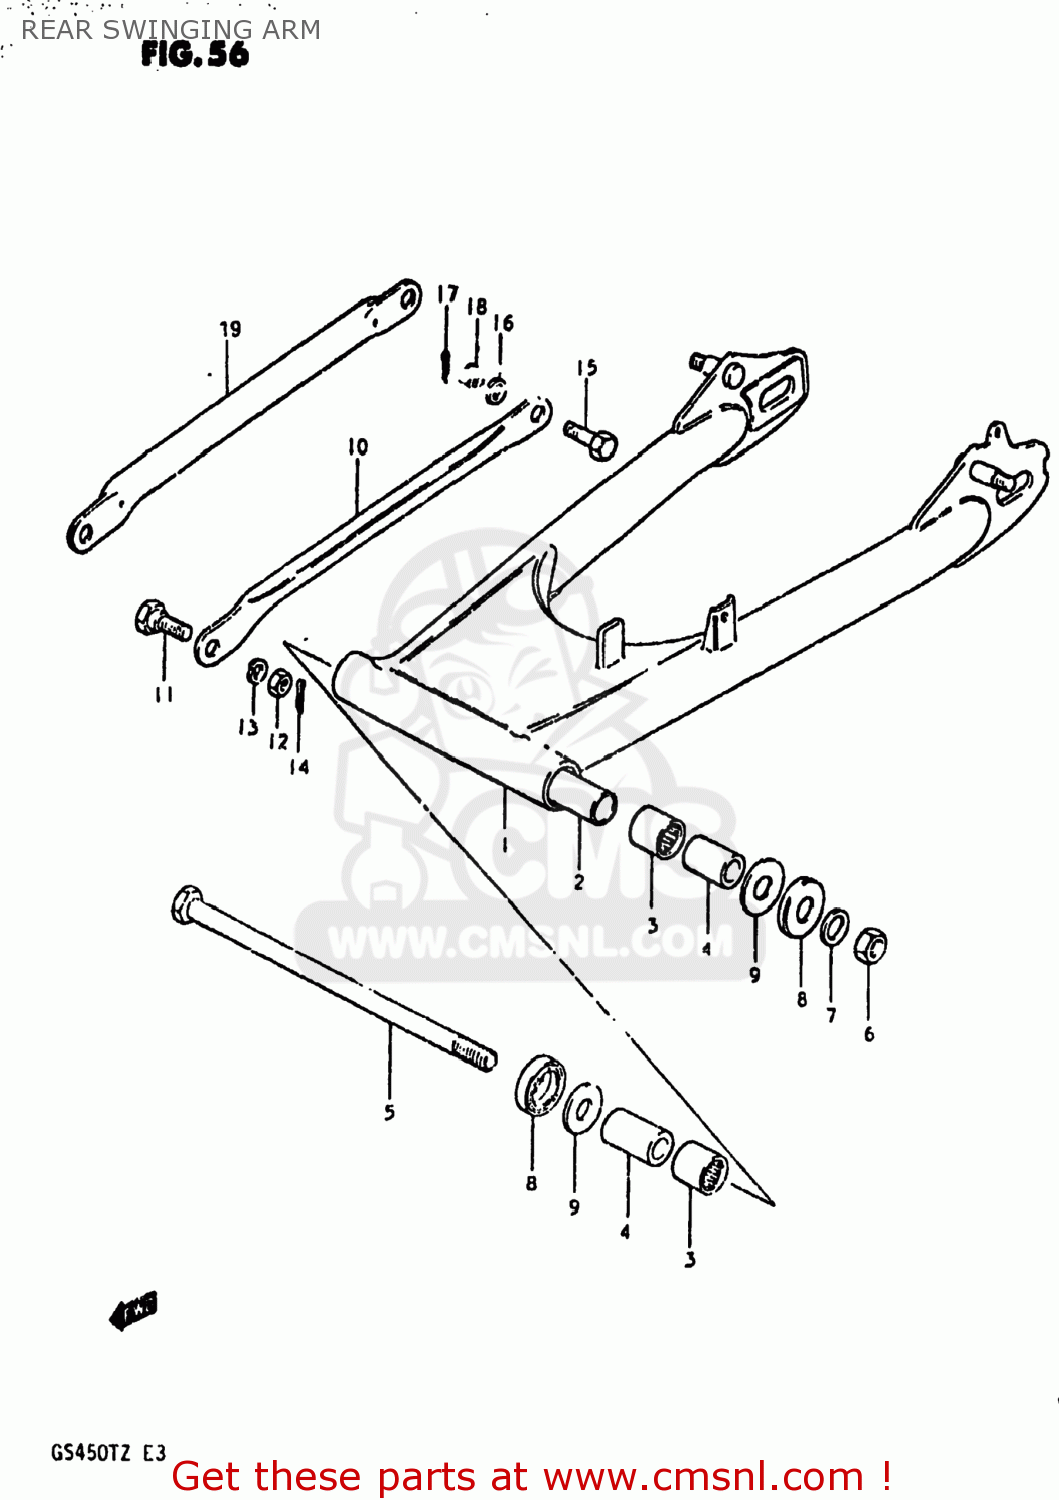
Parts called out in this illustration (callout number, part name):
1	ARM,REAR SWING
2	SPACER,SWINGINGARM CTR
3	BEARING(22X29X30)
4	SPACER,RR SWGARM PIVOT
5	SHAFT,REAR SWING ARM
6	NUT 14MM
7	WASHER
8	CVR,RR SWGARM DUST SEAL(OD:40)
9	WASHER(14.2X34X1)
10	TORQUE LINK,REAR
11	BOLT(10X24.5)
12	NUT
13	LOCK WASHER
14	PIN
15	BOLT(10X31)
16	LOCK WASHER
17	PIN
18	NUT
19	TORQUE LINK,REAR
